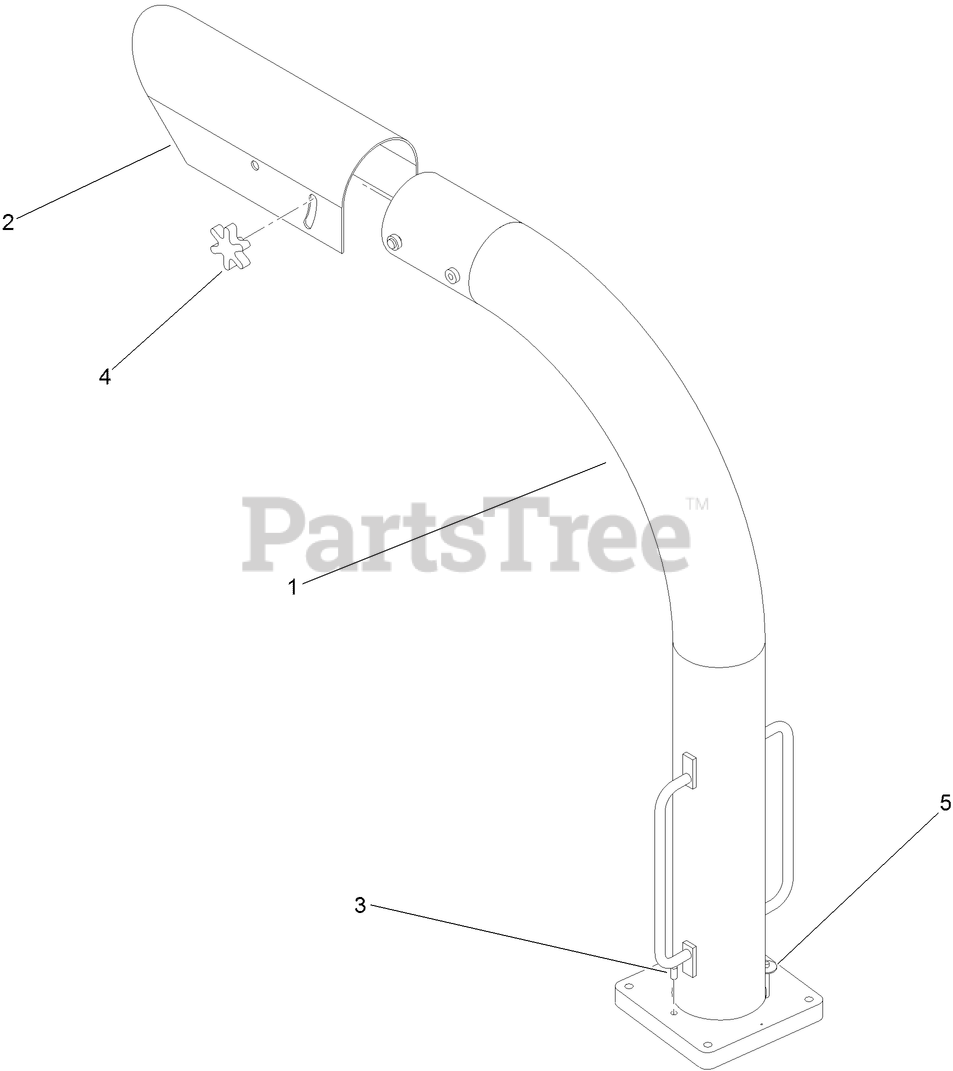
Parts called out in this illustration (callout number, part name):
1	EXIT CHUTE ASSEMBLY
2	PLATE-DEFLECTOR, CHUTE
3	PIN-DOWEL
5	PIN-LOCKING
